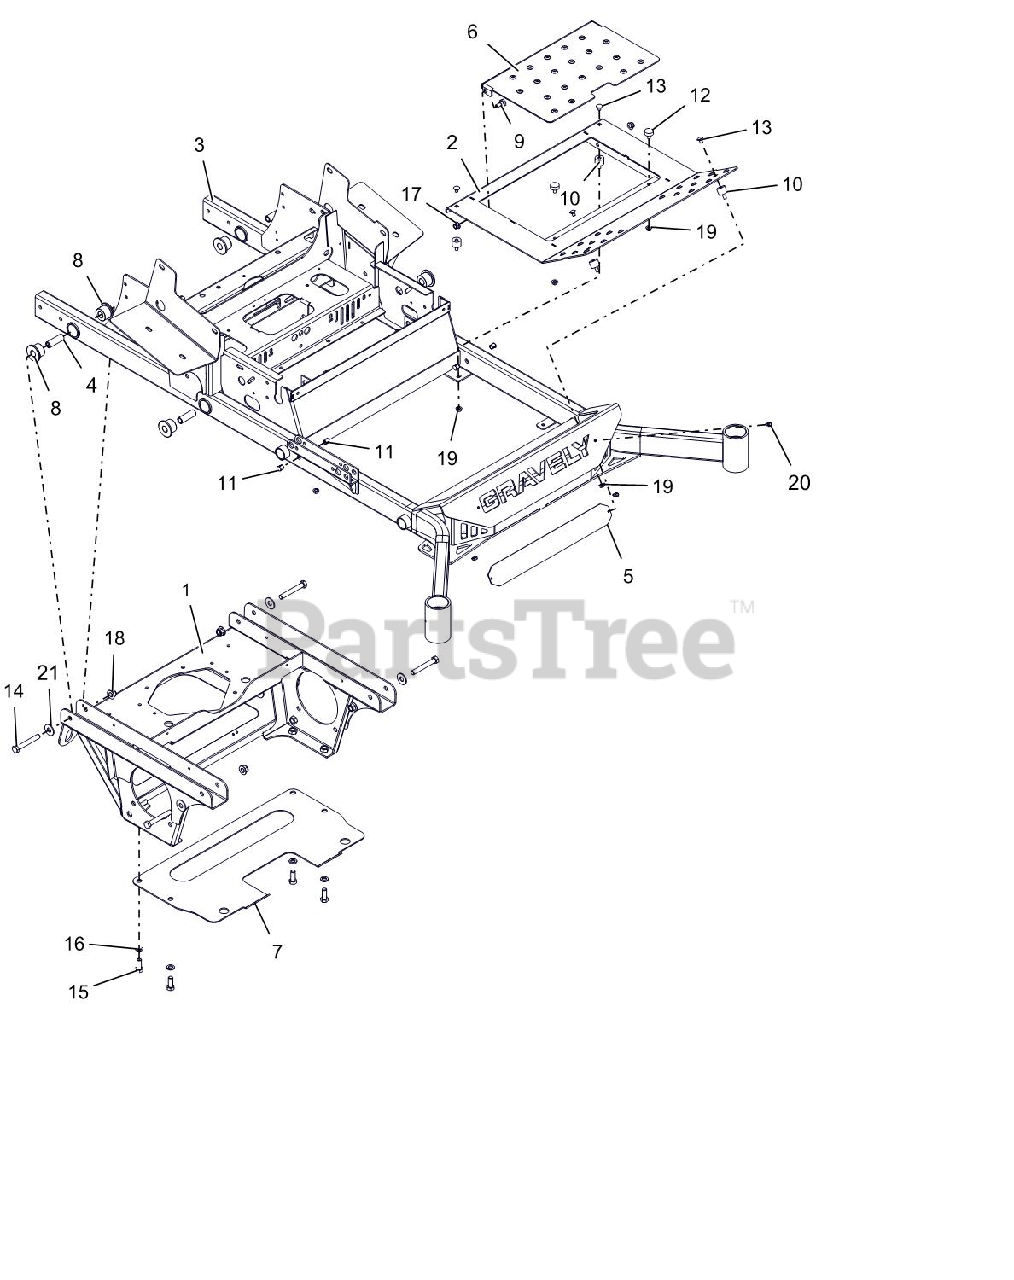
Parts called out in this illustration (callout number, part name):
1	PT200/400 AXLE/ENG FRM WMT-RED
2	FOOTPLATE WLDMT W/SAFETY DECAL
3	72" PT200/400 FRAME W/DECALS
4	BSHG-SLV .50X.75X2.23
5	BUMPER LOGO BACKING PLATE -BLK
6	INSPECTION PANEL W/SAFTY DECAL
7	PLATE-TRANSMISSION SKID
8	BSHG-FLG .75X1.51X1.13X2.0 URE
9	BLT,SHLDR EP .38-16X.30 HEX YZ
10	BUMPER,STUD MNTD W/FEMALE INSR
11	PLUG, HOLE .50
12	BUMPER, RUBBER
13	@BLT-RDHDSQNK .31-18X.50 G5YZ
14	@BLT-HEX .50-13X3.50 GR5 YWZC
15	@BLT-HEX .50-13X1.25 GR5 YWZC
16	@WSHR-LK .50X.125 REG YWZC
17	@NUT-LK-NYL-FLG .38-16 YWZC
18	@NUT-LK-NYL-FLG .50-13 YWZC
19	@NUT-SPNLK-FLG .312-18 YWZC
20	SCR-TAP .25-20X.50 HWH TR YWZ
21	@WSHR-FL-STL.563X1.38X.109YWZC
